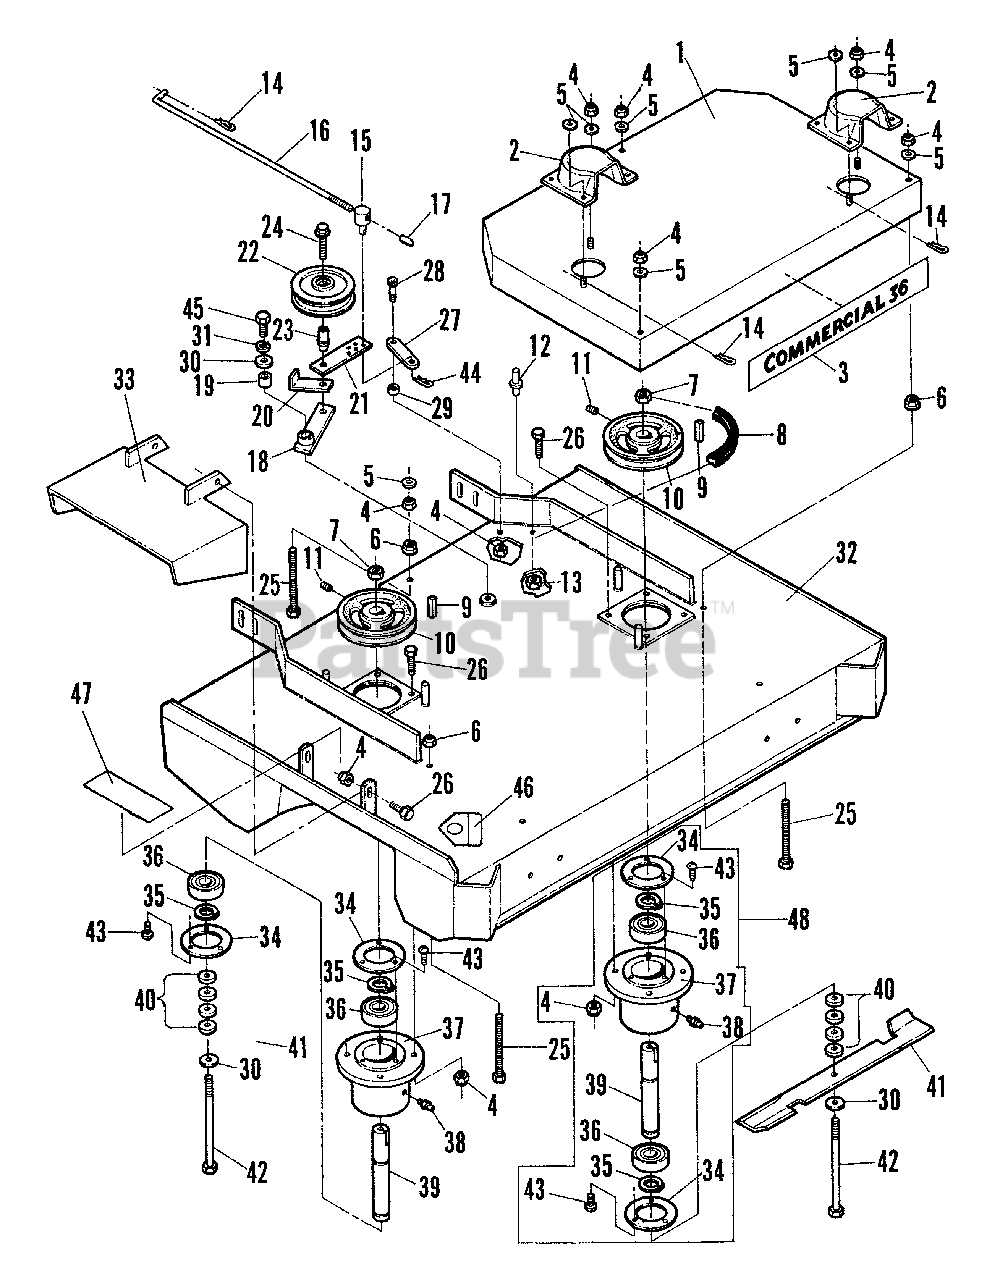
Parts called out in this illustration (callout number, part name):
1	SHIELD, Belt w/Decal 36
2	COVER, Spindle
3	DECAL, Commercial 36
4	NUT, 5/16-18 Hex Nyloc
5	WASHER, 5/16 Standard Flat
6	NUT, 5/16-18 Hex Flange Lock
7	NUT, 5/8-18 Hex
8	BELT, Engine Blade
9	KEY, 1/4" Square x 1-1/4"
10	PULLEY, w/Set Screws
11	SCREW, 5/16-18 x 3/8" Hex Socket Set
12	STUD, Stop
13	NUT, 3/8-16 Hex Flange Lock
14	HAIRPIN, #2 Cotter
15	SWIVEL
16	ROD, Blade Drive
18	ARM, Idler w/Bushing
19	BUSHING
20	SNUBBER, Belt
21	ARM, Tightening
22	PULLEY, Idler
23	BUSHING, Flange
24	BOLT, 3/8-16 x 1-3/4" Hex Flange Lock, Grade 5
25	SCREW, 5/16-18 x 3-1/4" Hex Head Cap
26	SCREW, 5/16-18 x 1" hex Head Cap, Grade 2
27	ARM, Blade Assist
28	BOLT, 3/8 x Knurled Socket Head Shoulder
30	WASHER, 5/8" Flat
31	WASHER, 5/8" Split Lock
32	DECK, Front 36 w/Decals
33	DEFLECTOR, Chute
34	CAP, Cutter Housing
35	RING, Snap
36	BEARING
37	HOUSING, Cutter
38	FITTING, 1/8 NPT Grease
39	SPINDLE, Cutter
40	SPACER, Blade
41	BLADE, 18" Ultra High Lift (.164)
42	SCREW, 5/8-18 x 7-1/2" Hex Head Cap
43	SCREW, #10-23 x 3/8" Pan Head
44	HAIRPIN, #4 Cotter
45	SCREW, 5/8-11 x 1" Hex Head Cap, Grade 5
46	DECAL,CPSC
47	DECAL, "Caution"
48	ASSEMBLY, Cutter Housing
